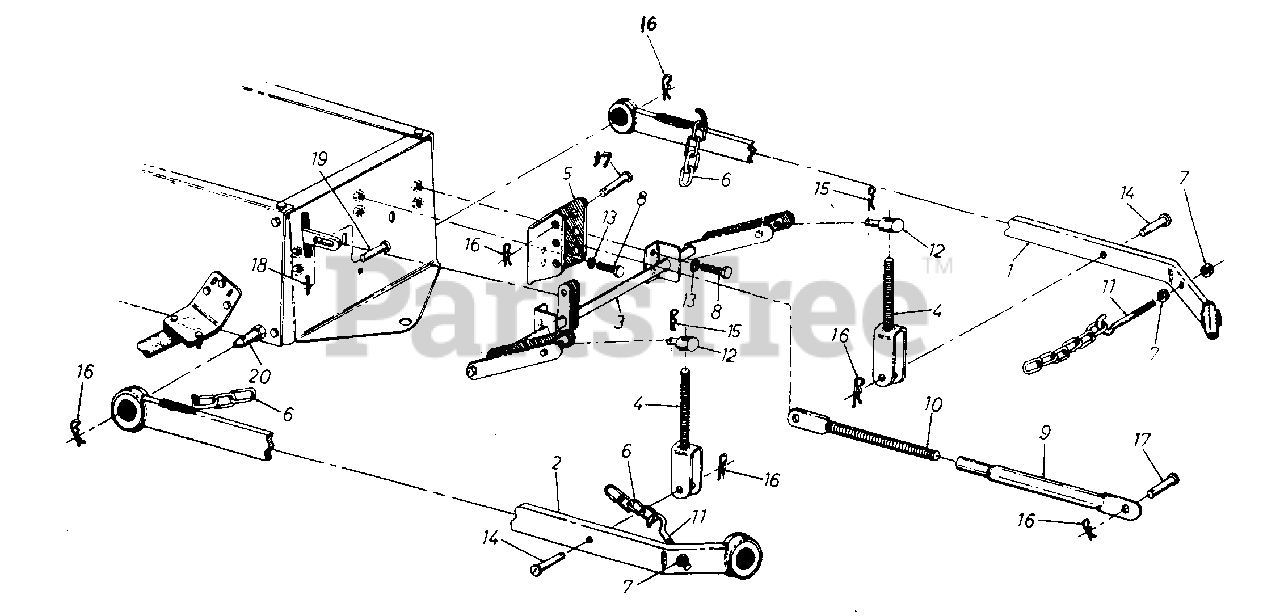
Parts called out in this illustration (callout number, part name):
1	Draft Bar Assembly-R.H.
2	Draft Bar Assembly-L.H.
6	Chain 20 links
7	Hex Cent. L.-Nut 7/16-14 Thd.
8	Hex Bolt 5-3/8-16 x Lg. Grade 5
10	Clevis Screw
11	Hitch Chain Hook
12	Clevis Pin
13	L.-Wash. 3/8" I.D.*
14	Clevis Pin 5/8 Dia. x 1.66 Lg.
15	Hairpin
16	Hairpin
17	Clevis Pin 5/8 Dia. x 2.4 Lg.
18	Cotter Pin 1/8 Dia. x 1-1/4 Lg.*
19	Clevis Pin
20	Link Clevis Pin
